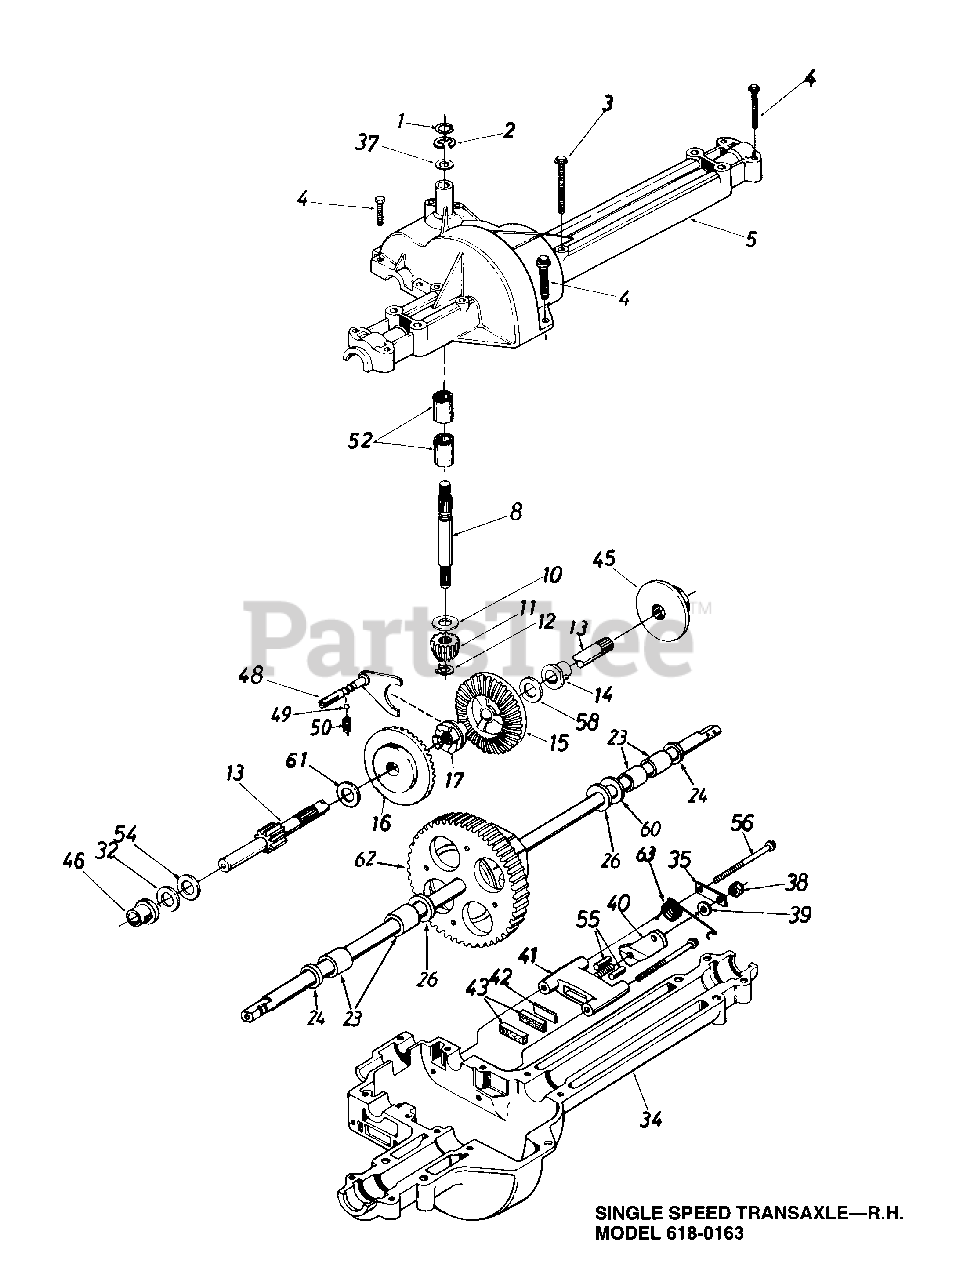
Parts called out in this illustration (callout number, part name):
1	Wire Ring
2	"E" - Ring
3	Hex Wash. TT-Tap Scr. 1/4-20 x 1.75" Lg.
4	Hex Tap Scr. 1/4-20 x 1.25" Lg.
5	Upper Housing
8	Input Shaft
10	Thrust Washer 5/8" I.D. x 1.25" O.D.
11	Pinion Input 14T
12	Retaining Ring
13	Drive Shaft - R.H. Brake
14	Flange Brg. 5/8" I.D. x 3/4" Lg.
15	Bevel Gear 42T Small I.D.
16	Bevel Gear 42T Large I.D.
17	Clutch Collar
23	Sleeve Bearing 3/4" I.D. x 1.0" Lg.
24	Oil Seal 3/4" I.D.
26	Fl-Wash. .760" I.D. x 1.5" O.D.
32	Washer
34	Lower Housing
35	Anti-Rotation Brkt.
37	Washer (See Below)
38	Hex Nut 5/16-24 Thd.
39	Fl-Wash. 344" I.D. x .875" O.D
40	Actuating Arm
41	Brake Yoke
42	Puck Plate
43	Brake Puck
45	Brake Disc
46	Flange Bearing 5/8" I.D. x 15/16" Lg
48	Shift Fork Ass'y
49	Ball Detent 250" Dia.
50	Spring Detent
52	Needle Brg 5/8" I.D. x 1/2" Lg.
54	Fl-Wash. 5/8" I.D. x 1" O.D. x .020 Thk
55	Actuating Pin 5/16" Dia
56	Hex Wash Hd Self-Tap Scr 1/4-20 Thd 1/4-20 Thd
58	Fl-Wash 5/8" I.D. x 1" O.D. x .020 Thk
60	Washer (See Below)
61	Thrust Washer
62	Differential Ass'y.
63	R.H. - Brake Spring
